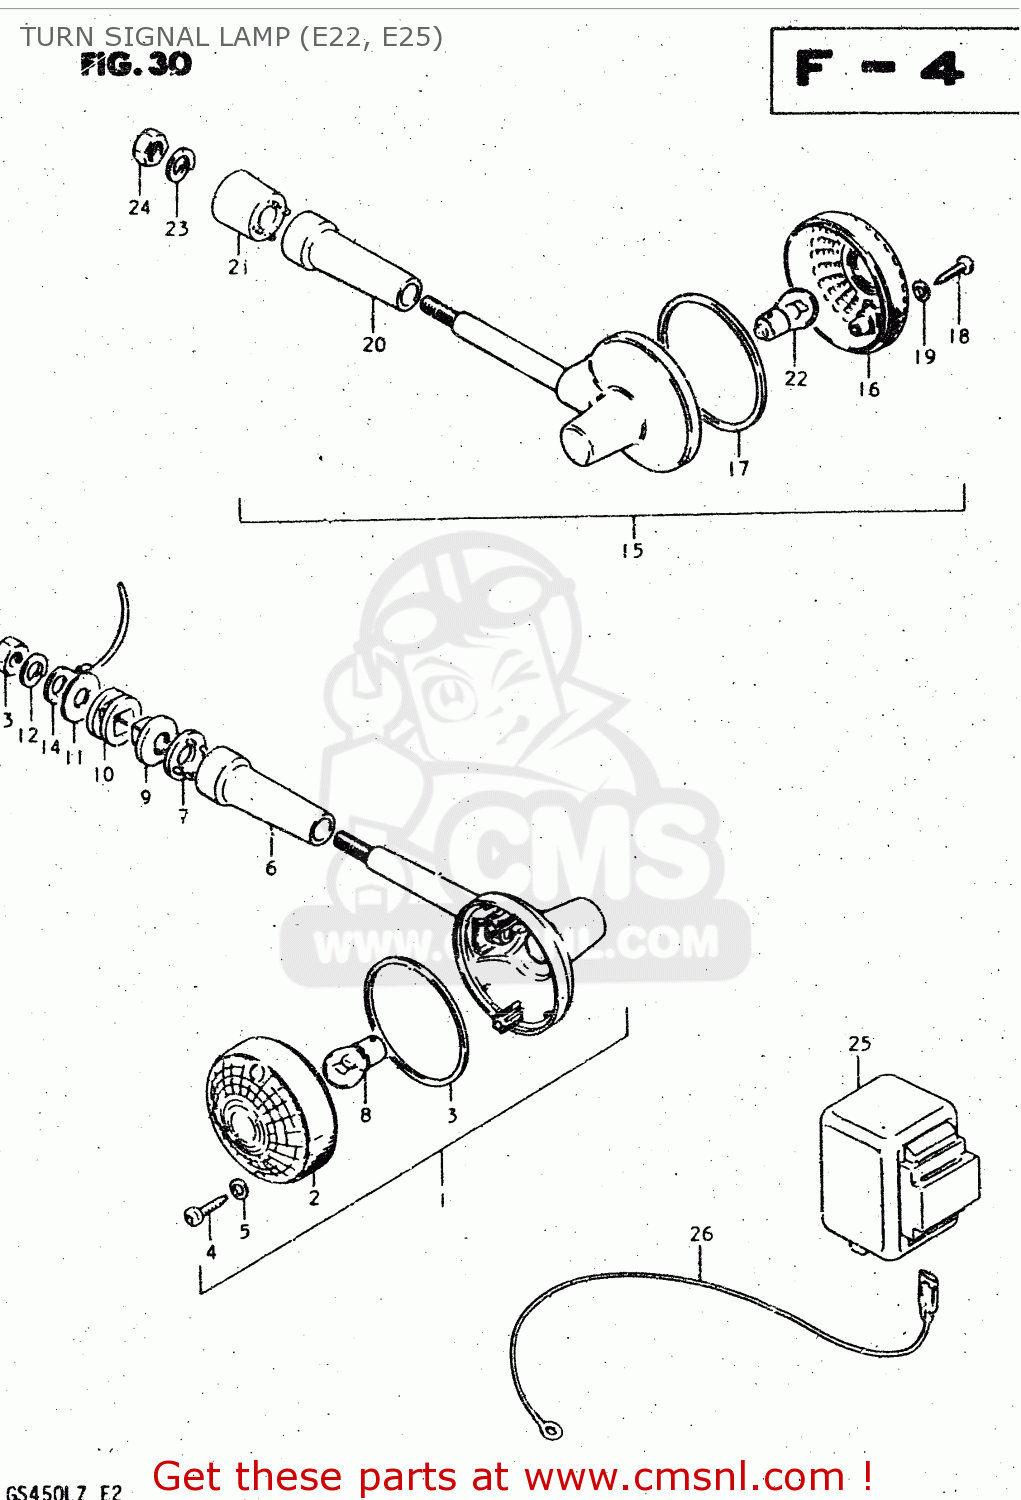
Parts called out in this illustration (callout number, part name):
1	LAMP ASSY,FR T
2	LENS
3	GASKET (NAS)
4	SCREW
5	GASKET (NAS)
6	COVER,STAY
7	CUSHION
8	BULB(12V21W)
9	SPACER
10	CUSHION
11	WASHER (10.5X30X2.3)
12	LOCK WASHER
13	NUT
14	LEAD WIRE,EARTH
15	LAMP ASSY,RR T
16	LENS
17	GASKET (NAS)
18	SCREW
19	GASKET (NAS)
20	COVER,STAY
21	CUSHION
22	BULB(12V21W)
23	LOCK WASHER
24	NUT
25	RELAY, TURN SIGNAL
26	LEAD WIRE, RELAY EARTH
